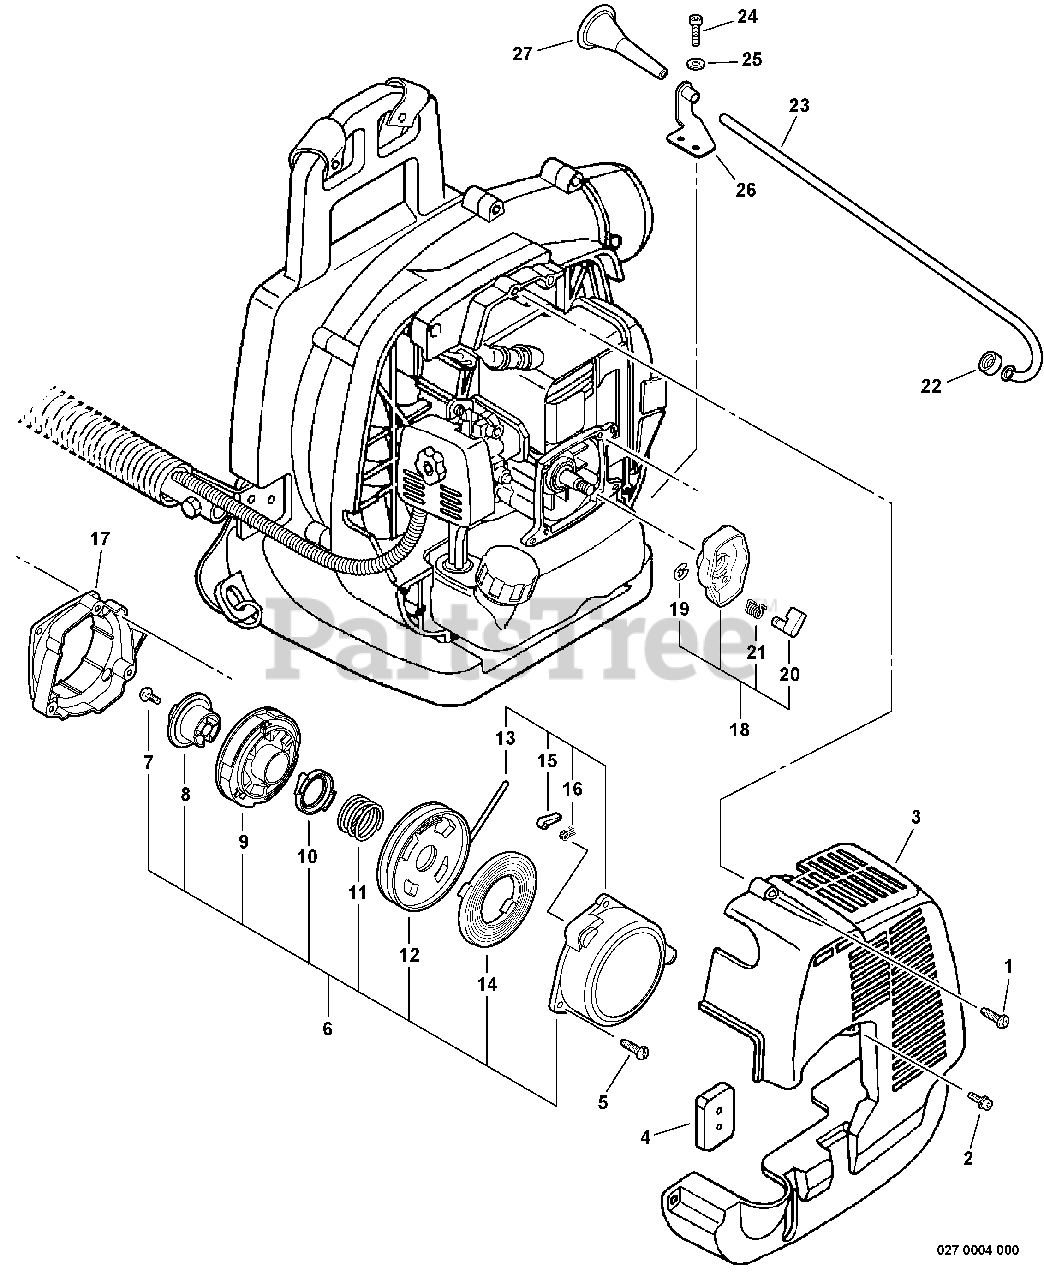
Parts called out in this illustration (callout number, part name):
1	SCREW, TAPPING 5×20
2	BOLT 4×16
3	COVER, ENGINE
4	CUSHION
5	SCREW, TAPPING 5×20
6	STARTER ASSY
8	PLATE, CAM
9	SPRING ASSY
10	PAWL, STARTER
11	SPRING, RETURN
12	PULLEY, STARTER
13	ROPE, STARTER
14	SPRING, RECOIL
15	PAWL, STARTER
18	PAWL ASSY, STARTER
19	E-RING 4
20	PAWL, STARTER
21	SPRING, RETURN
22	CUSHION
23	GUIDE, ROPE
24	BOLT 5×12
25	WASHER 5.5×16×2T
26	BRACKET, ROPE GUIDE
27	GRIP, STARTER
